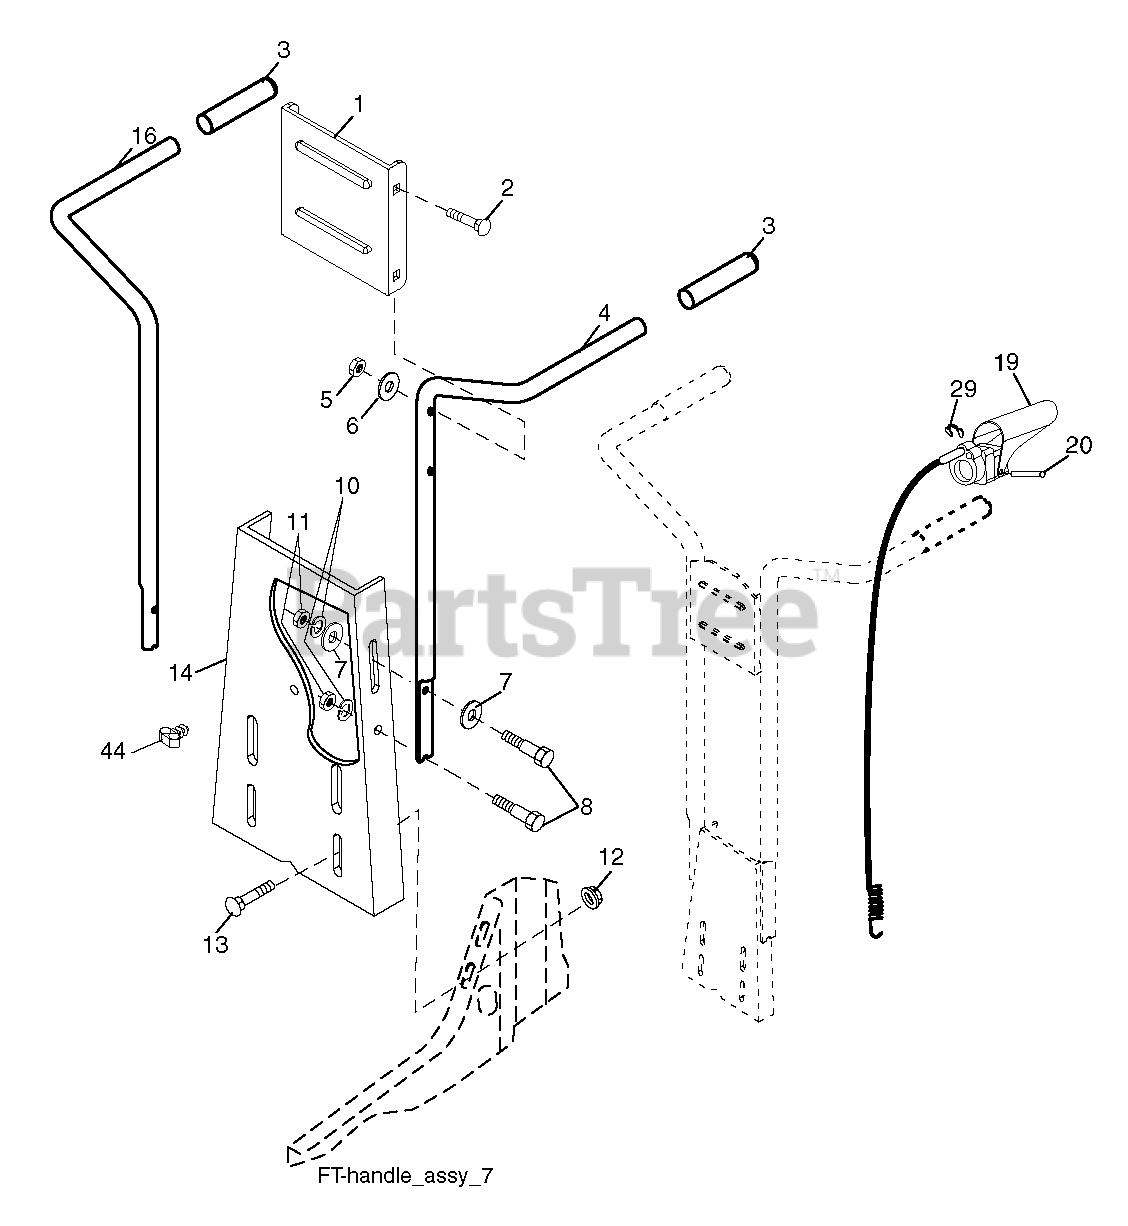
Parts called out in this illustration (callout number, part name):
1	BRACKET.HANDLE.TILLER.YELLOW
3	GRIP.HANDLE.BLACK
4	HANDLE.LH.D.BEND.BLACK
6	WASHER
7	WASHER
8	BOLT
10	LOCKWASHER
13	BOLT, RDHD SQNK 5/16-18 X 3/4
14	PANEL.HANDLE.RT TILLER.YELLOW
16	HANDLE.RH.D.BEND.BLACK
19	CONTROL ASM.TINE.49.88
20	PIN, PIVOT
29	RETAINING.RING.#5103-25
44	CLIP.ROUTING DUAL
